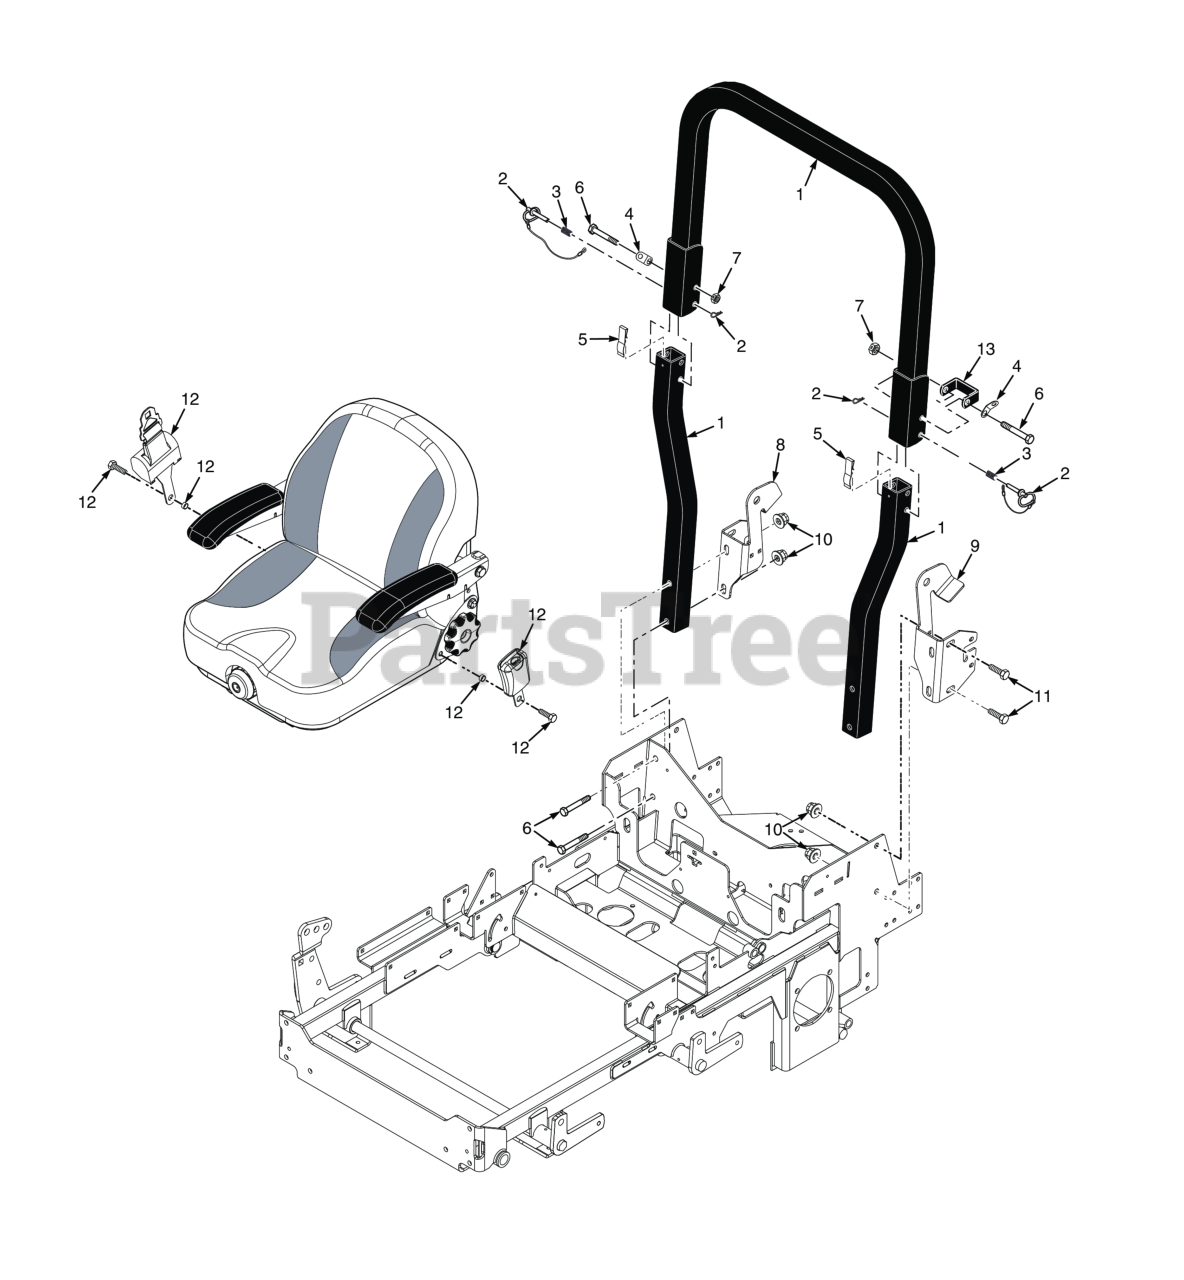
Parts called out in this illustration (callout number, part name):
1	ROPS Assembly, Foldable
1	ROPS ASSY, FOLDABLE
2	Pin Assembly, ROPS Hinge
3	Spring, ROPS
4	Clip, ROPS
5	Spring, ROPS Anti-Rattle
6	Bolt, Hex Head, 1/2-13 x 3-1/4"
7	Locknut, Hex 1/2-13 Center Lock
8	ROPS Mount, RH
9	ROPS Mount, LH
10	Nut, Elastic Stop 1/2-13, (STT-52 & STTII-52)
11	Bolt, Hex Head 1/2-13 x 1-1/4"
12	Seat Belt Kit (Suspension Seat)
12	Seat Belt Kit (Soft Ride Seat)
